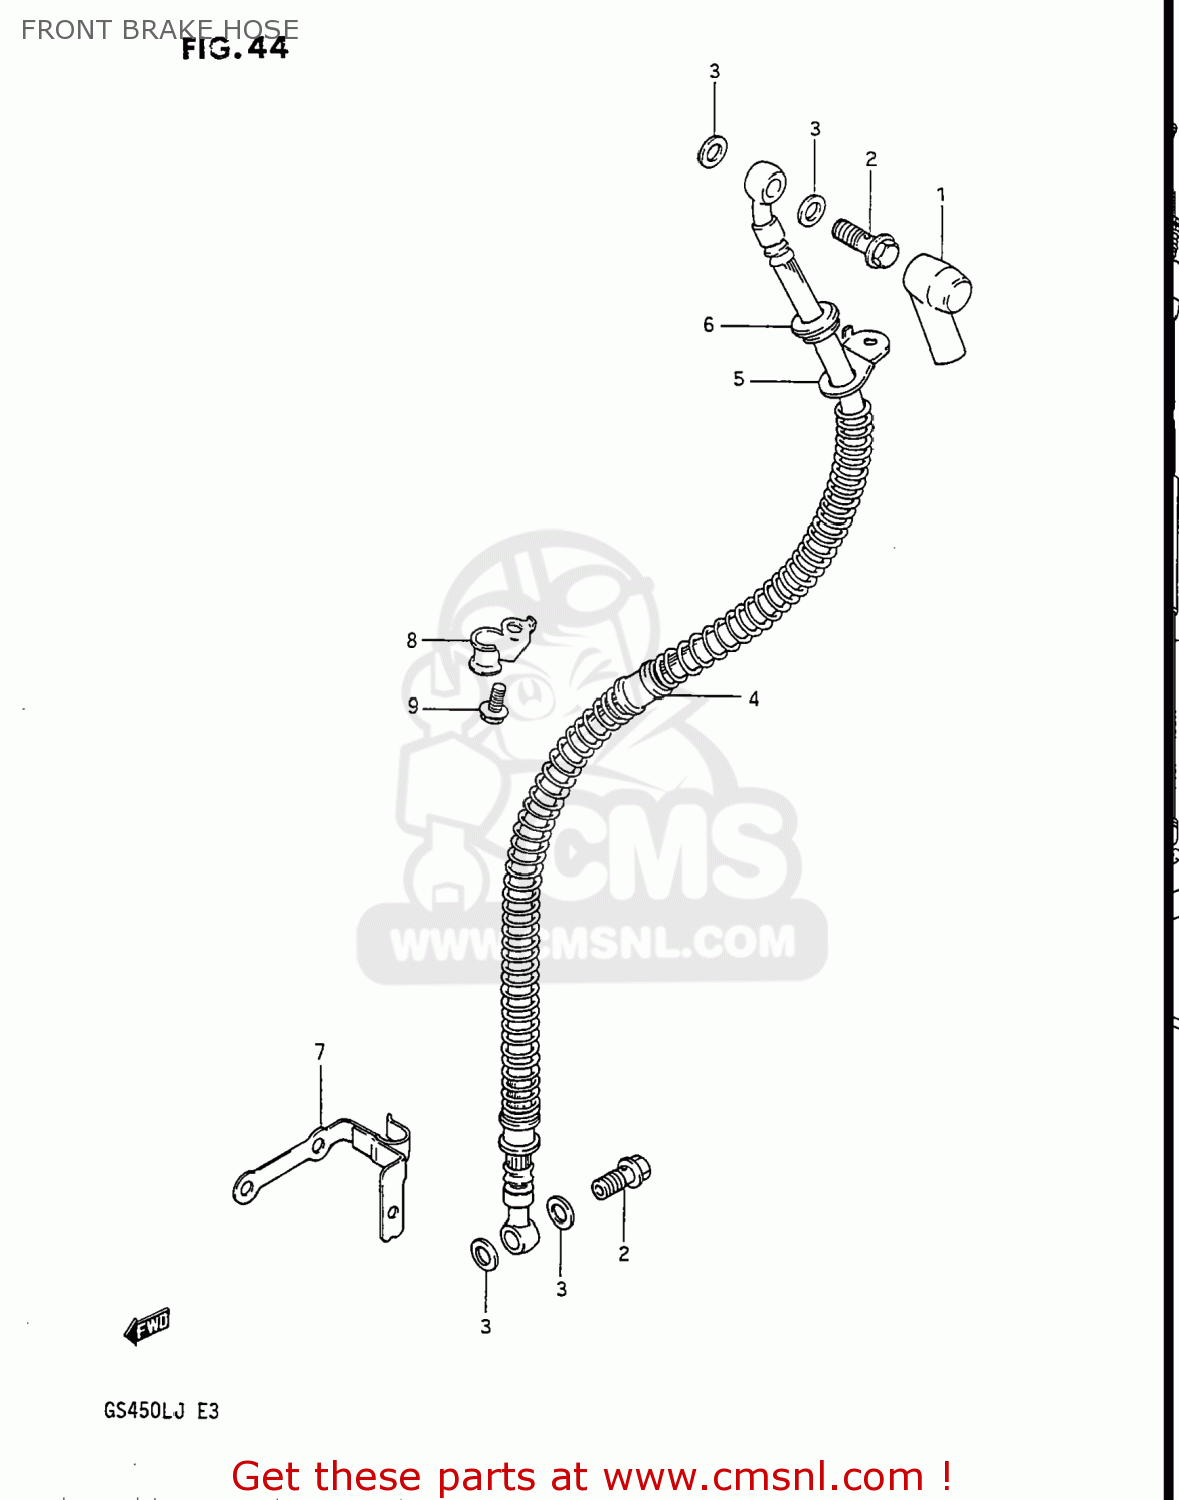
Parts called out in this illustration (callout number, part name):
1	BOOT,MASTER CYLINDER
2	BOLT UNION
3	WASHER(10X15X1.5)
4	HOSE,BRAKE
5	GUIDE,BRAKE HOSE
6	GROMMET
7	CLAMP,BRAKE HOSE,LEFT
8	GUIDE,BRAKE HOSE NO.3
9	BOLT
